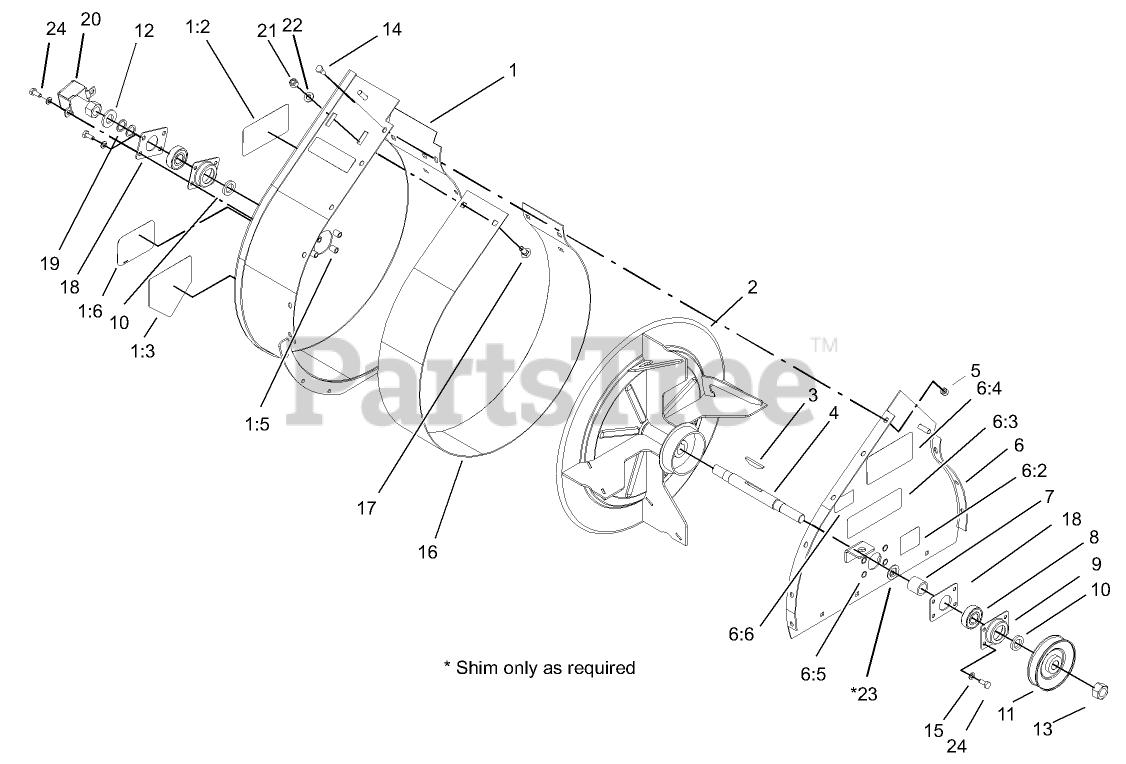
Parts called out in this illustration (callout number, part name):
1	BLOWER HOUSING ASM
1:2	DECAL-DANGER
1:3	DECAL-DANGER
1:5	INSERT-NUT
1:6	DECAL
2	IMPELLER ASM
4	Shaft-Blower
5	NUT-LOCK, NI
6	COVER PLATE ASM
6:2	DECAL-WARNING
6:3	DECAL-DANGER
6:4	DECAL-DANGER
6:5	INSERT-NUT
6:6	DECAL-PROTECTION, EAR
7	Spacer
8	BEARING-BALL
9	CUP-BEARING
10	SPACER-BEARING
11	Pulley ASM
12	WASHER-FLAT
13	NUT-HEX
14	SCREW-HH
15	WASHER-LOCK
16	STRIP-WEAR
17	BOLT-CARR
18	PLATE-COVER
19	WASHER-FLAT
20	Cover-Shaft
21	NUT-LOCK, NI
22	WASHER-PLAIN
23	WASHER-THRUST
24	SCREW-HH
